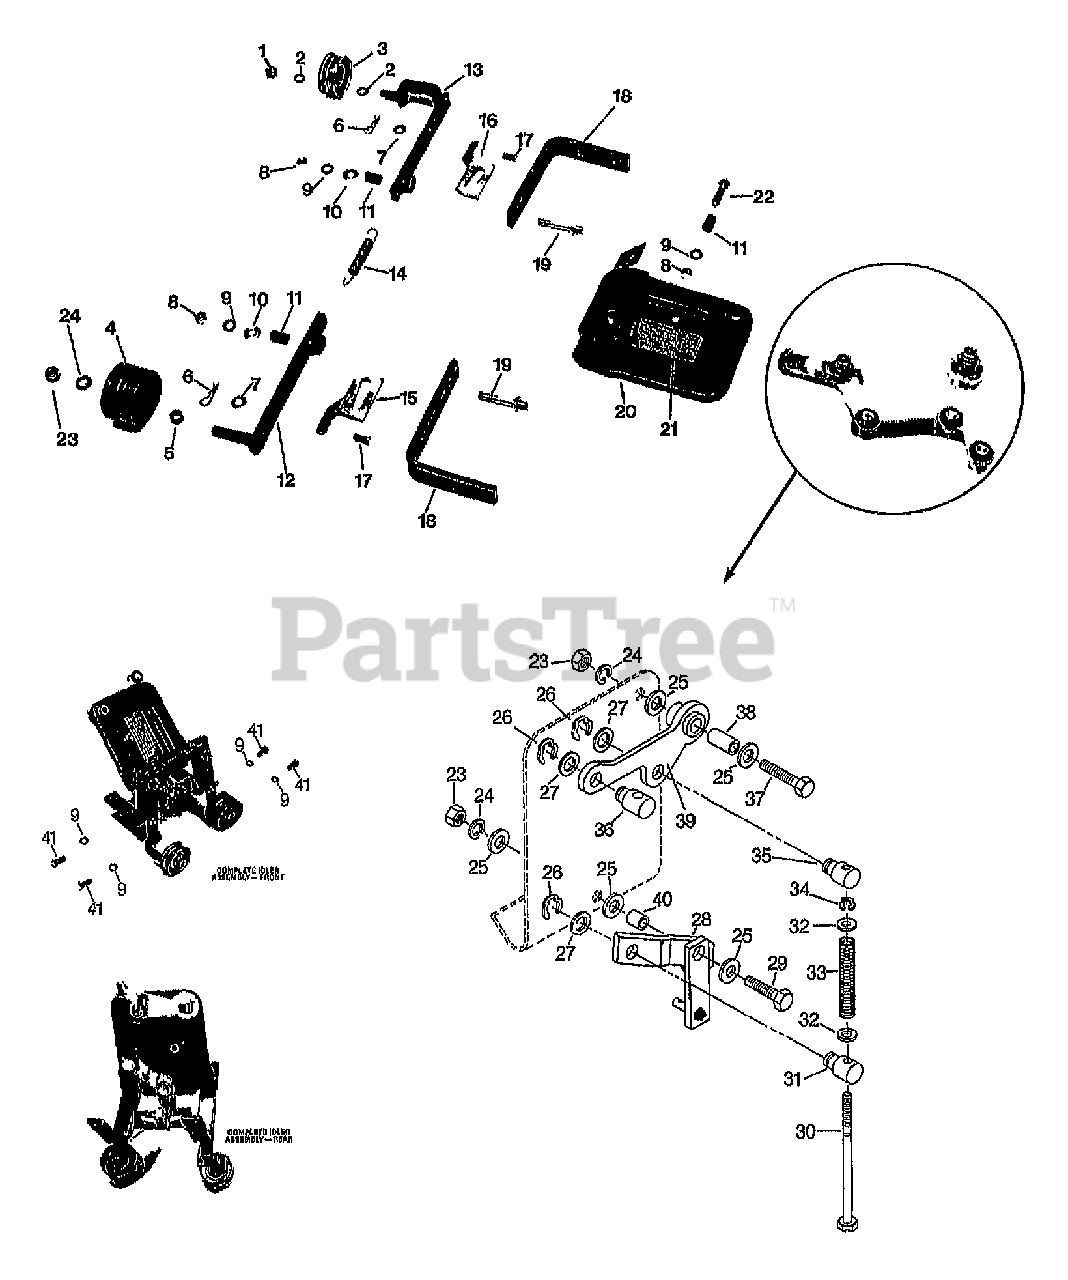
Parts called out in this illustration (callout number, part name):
1	NUT-H/LK 3/8-16
2	BUSHING-.54X.38X.08
3	IDLER-REV
4	PULLEY-FWD IDLER
5	BUSHING-.5X.375X.3
6	PIN-CLIP .08
7	WASHER-FLAT 1/4 SAE
8	NUT-HEX 5/16-18 ZP
9	WASHER-LK .312 ZP
10	WASHER-#.75X.32X.09 ZP
11	BUSHING-.438X.323X.712
12	ARM-IDLER FWD PNT
13	ASSM-IDLER REV @ DEPL
14	SPRING-.436 X 3.25
15	LINK-FWD
17	PIN-CLEVIS .375X.719 ZP
18	BAR-MTG PNT
19	STUD 5/16-18X2.145 ZP
20	BASE-SHIFTING W/DECAL (INCL. #50112 WARNING DECAL)
21	DECAL-BELT (WARNING INSTRUCTIONS ON BELTS/ PULLEYS)
22	SCR-HH 5/16-18X1.25 G5ZP
23	NUT-HEX 3/8-16 ZP
24	WASHER-LK .375 @ DEPL
25	SPACER-.88X.385X.09 ZP
26	RING-KLIP .500 ZINC
27	WASHER-#.88X.51X.063 ZP
28	BELLCRANK-WELDMENT
29	SCR-HH 3/8-16X1.25
30	SCR-HH 1/4-20X4.5 G5
31	PIVOT-SLIDE
32	WASHER # ZP (BETWEEN LOWER PIVOT & SPRING BETWEEN SPRING AND RETAINING RING)
33	SPRING-.52 X 3
34	RING-KLIP 5304-25
35	PIVOT-THREADED
36	PIVOT-ROD
37	SCR-HXSKT 1/4-20X.625
38	BUSHING-.5X.38X.815 (REPLACED BY #9060)
39	KIT-RODCRANK (REPLACED BY #20719)
40	BUSHING-.5X.38X.4
41	SCR-HH 5/16-18X1.0 G5 ZP
